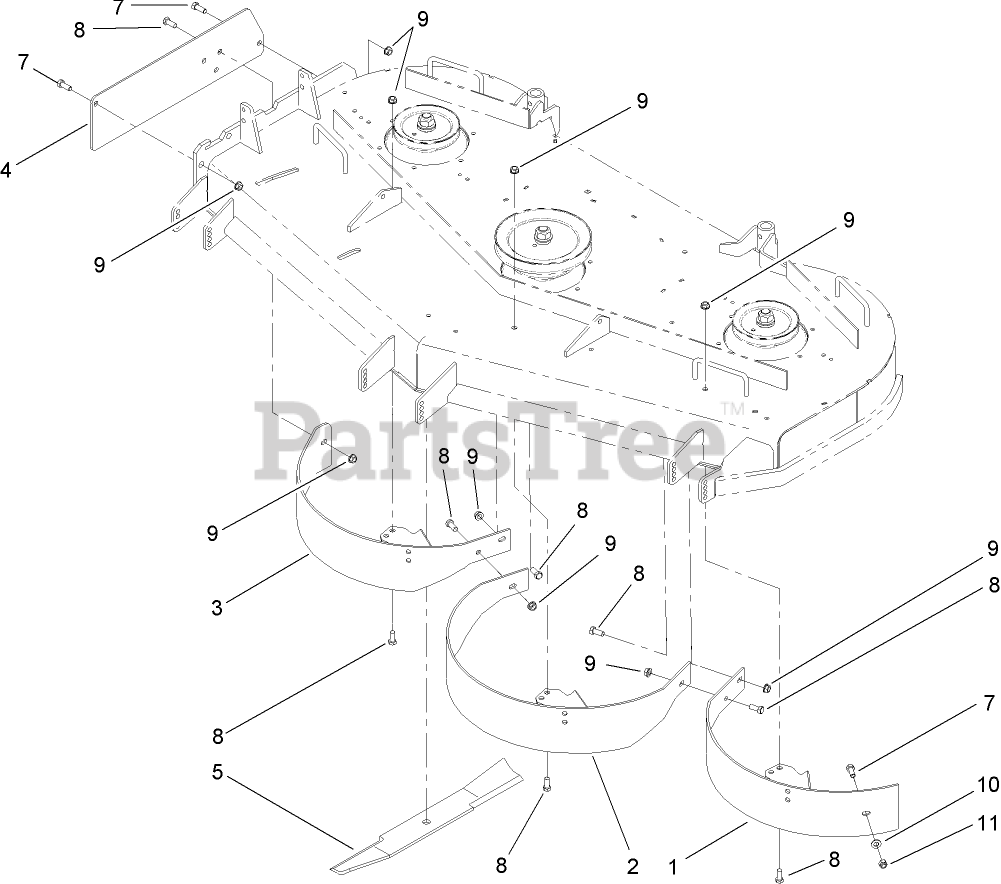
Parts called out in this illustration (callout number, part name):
1	LH BAFFLE ASM
2	CENTER BAFFLE ASM
3	RH BAFFLE ASM
4	PLATE-DISCHARGE
5	BLADE-RECYCLER, 20.5 INCH
7	SCREW-HH
8	SCREW-HH
9	NUT-HHF, WHIZ
10	WASHER-FLAT
11	NUT-LOCK, NI
